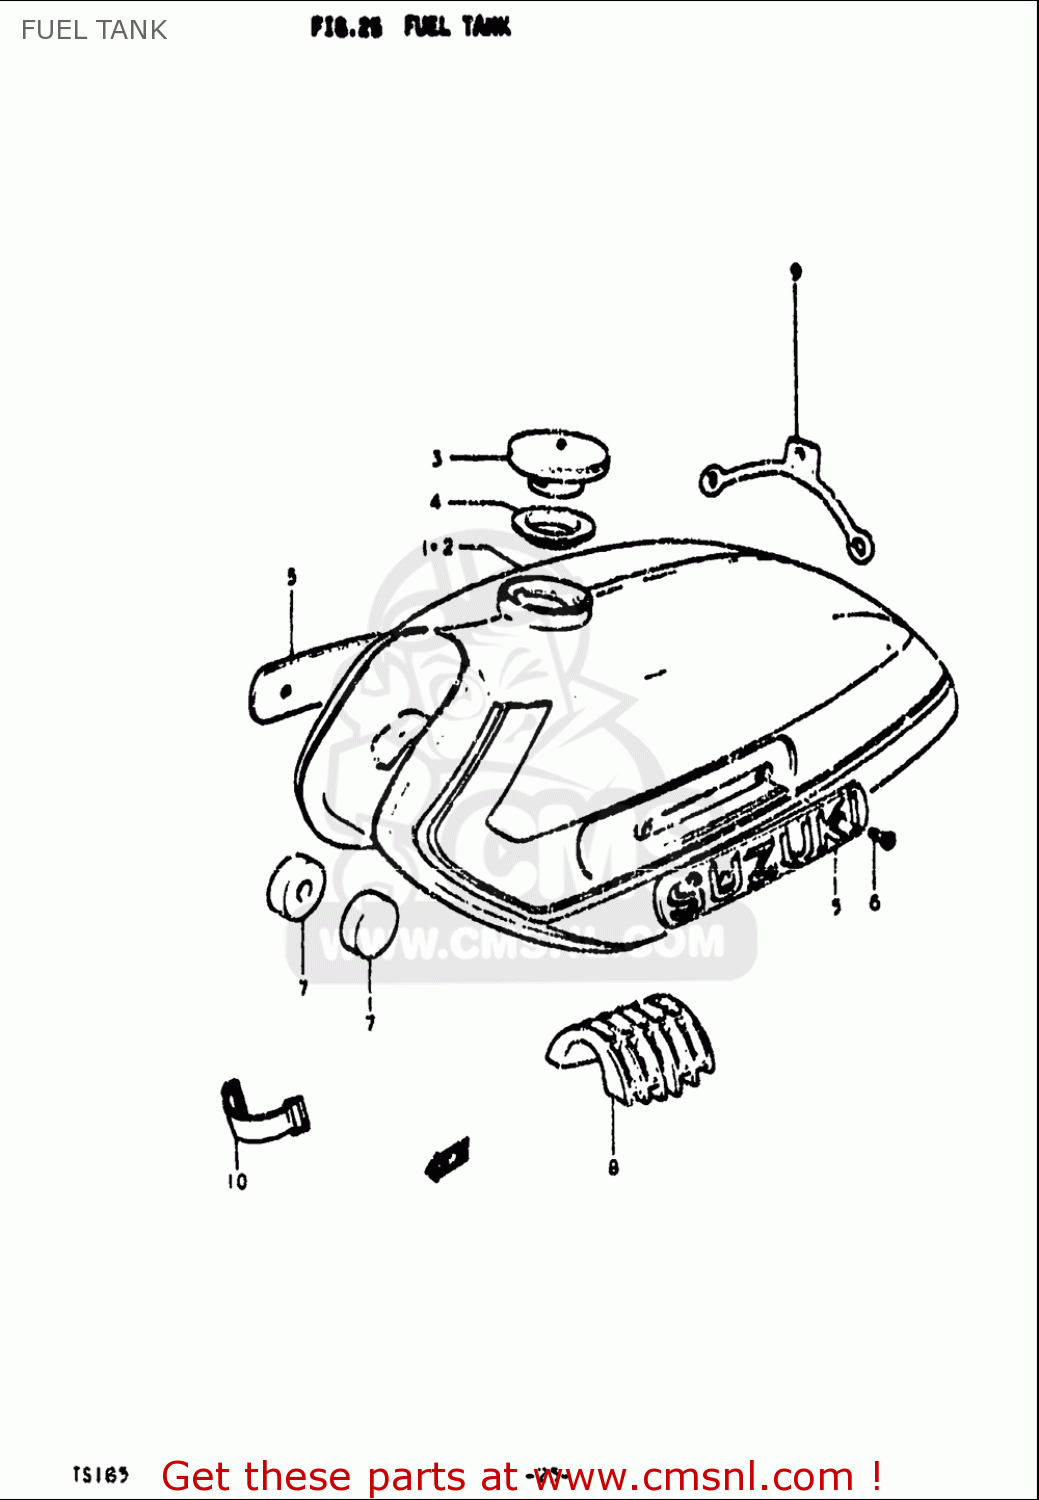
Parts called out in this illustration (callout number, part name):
3	CAP ASSY,FUEL TANK FILLER
4	GASKET (NAS)
6	SCREW
7	CUSHION
8	CUSHION
10	BAND
